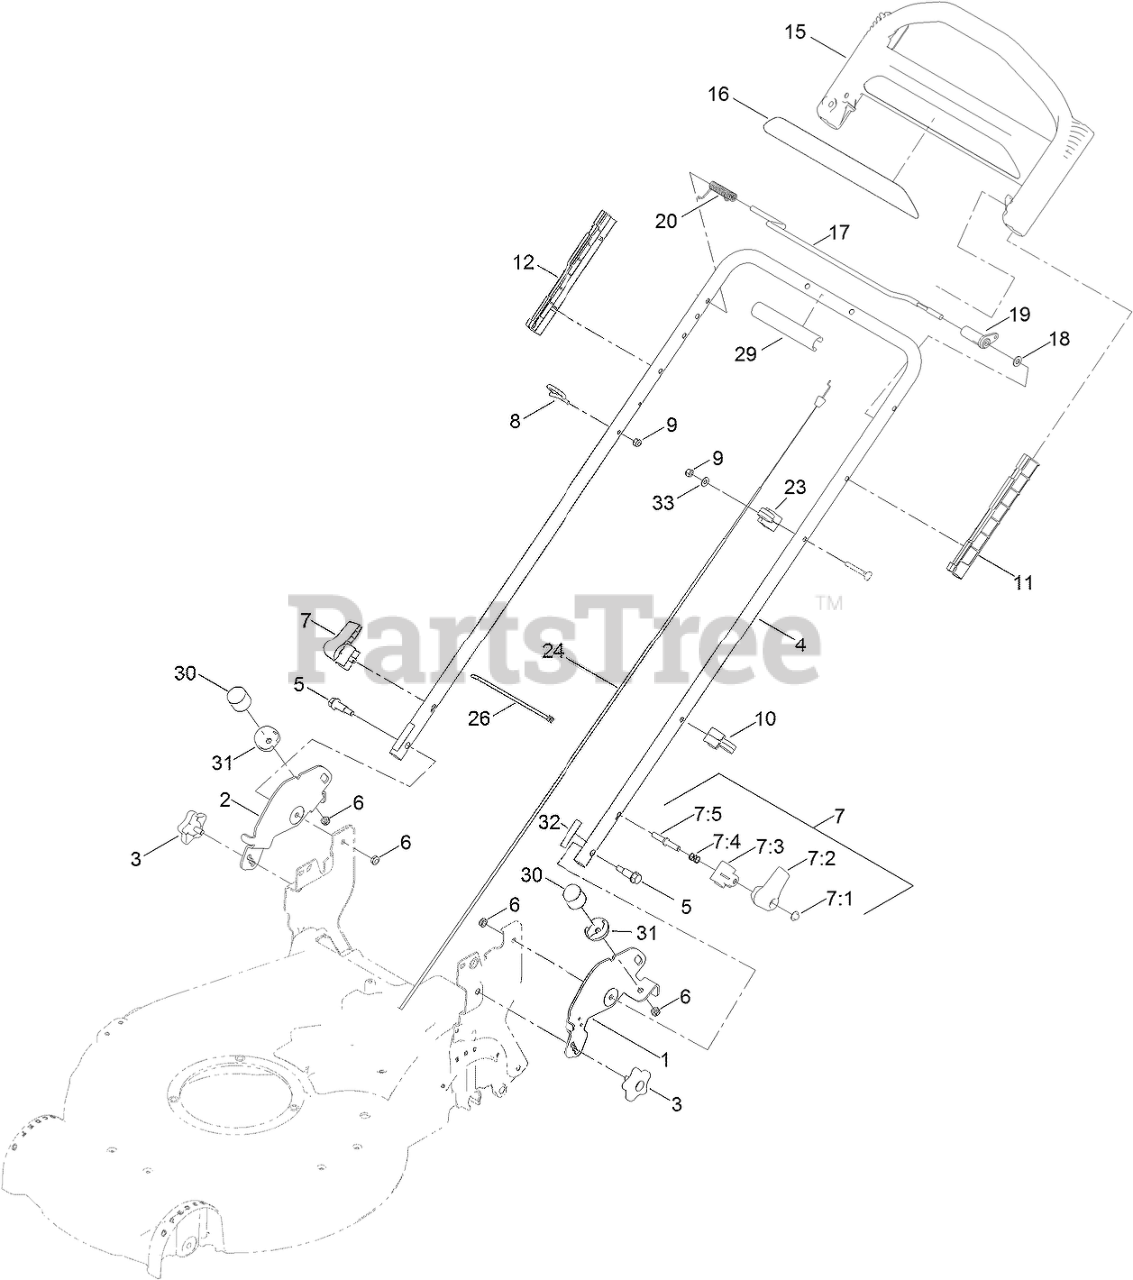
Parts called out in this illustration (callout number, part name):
1	BRACKET-FLOAT, LH
2	BRACKET-FLOAT, RH
3	KNOB-HANDLE
4	HANDLE-UPPER
5	BOLT-SHOULDER
6	NUT-LOCK, NI
7	QUICK RELEASE ASM
7:1	NUT-PUSH
7:2	LEVER-RELEASE
7:3	ANCHOR-SPRING
7:4	SPRING-COMPRESSION
7:5	ROD-RELEASE
8	GUIDE-ROPE
9	NUT-LOCK, NI
10	GUIDE-CABLE
11	GUIDE-LH
12	GUIDE-RH
15	HANDLE-CONTROL
17	BAR-CONTROL, TRACTION
18	WASHER-PLAIN
19	LEVER-TRACTION
20	SPRING-TORSION
23	ANCHOR-CABLE
24	CABLE-TRACTION
26	TIE-CABLE
29	HANDLE-COVER
30	BUMPER-RUBBER
31	COVER-BUMPER
32	DECAL-FLEX
33	WASHER-FLAT
